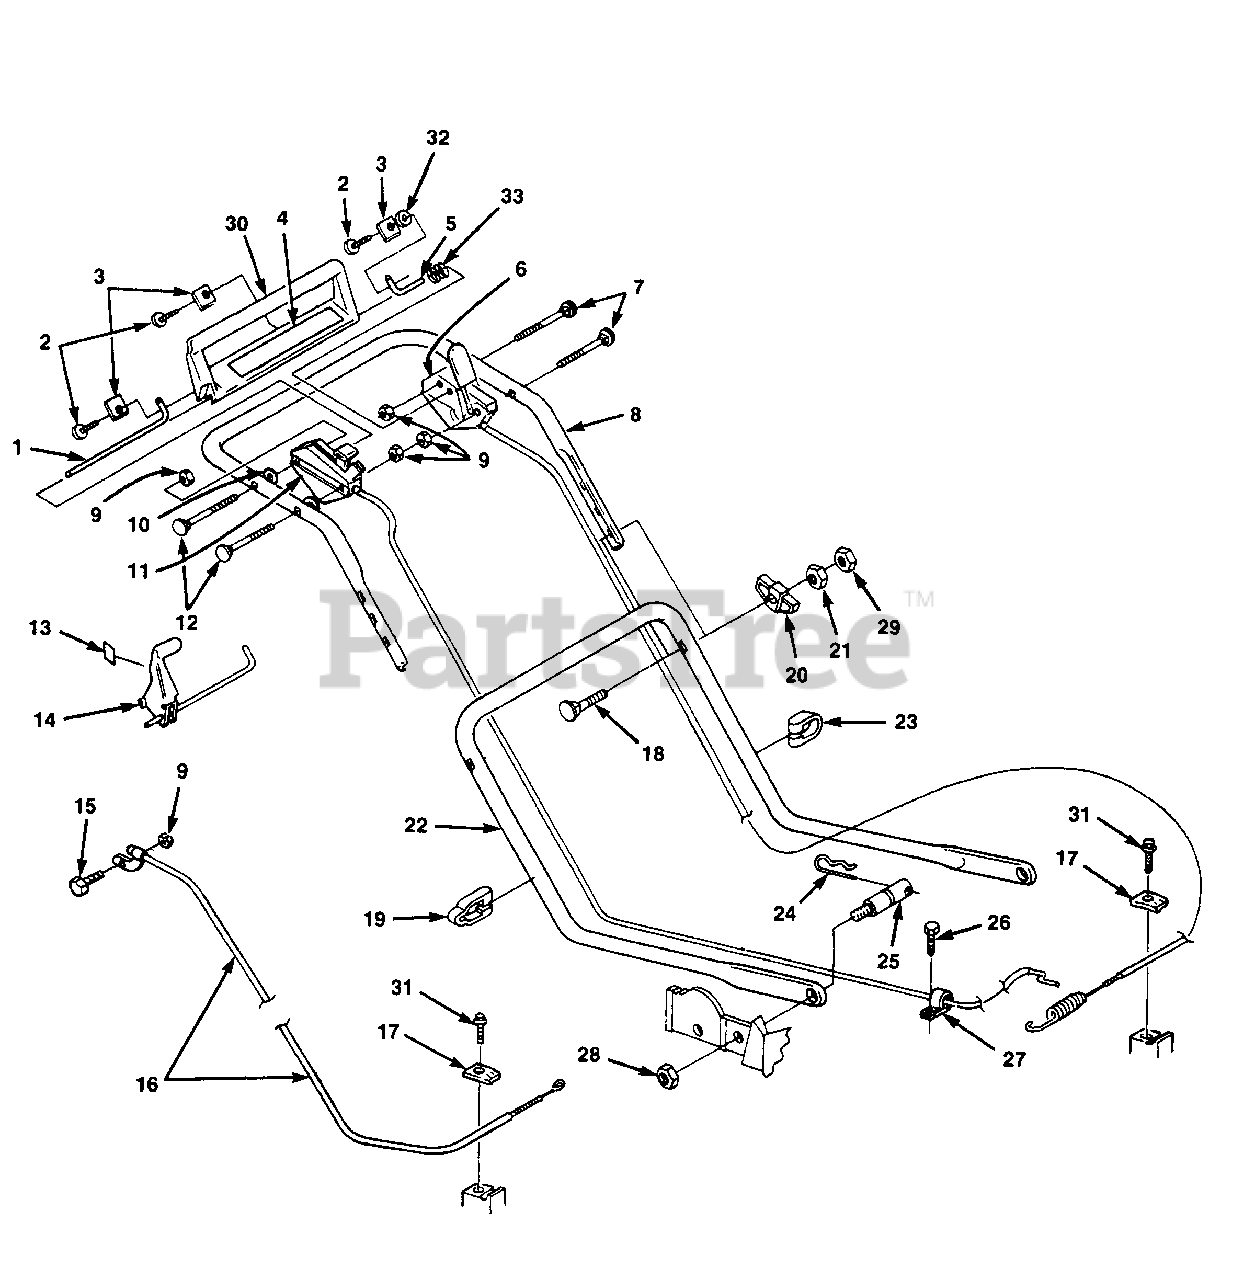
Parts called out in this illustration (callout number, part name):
1	SHAFT- Pivot
2	SCREW- 1/4-10 x 5/8
3	CLAMP- Pivot shaft
4	DECAL- Brake bail
5	SHAFT- Pivot
6	CONTROL- Blade/Brake/Clutch
7	BOLT- Sq. Nk.
8	HANDLE- Upper
9	NUT- Hex 1/4-20
11	CONTROL- Throttle
12	BOLT- Sq. Nk.
13	DECAL
14	LEVER- Assembly-Traction
15	SCREW- 1/4-20 x 1 1/2
16	CABLE- Traction
19	CLAMP- Cable double
20	KNOB- Handle
21	NUT- Hex 5/16 x 18
22	HANDLE- Lower
23	CLAMP- Cable single
24	PIN- Cotter hair
26	SCREW- 1/4-20 x 3/4
28	NUT- Flange 5/16-18
29	NUT- Lock 5/16 x 18
30	BAIL- Brake control
31	SCREW- 1/4-20 x 5/8
32	WASHER
